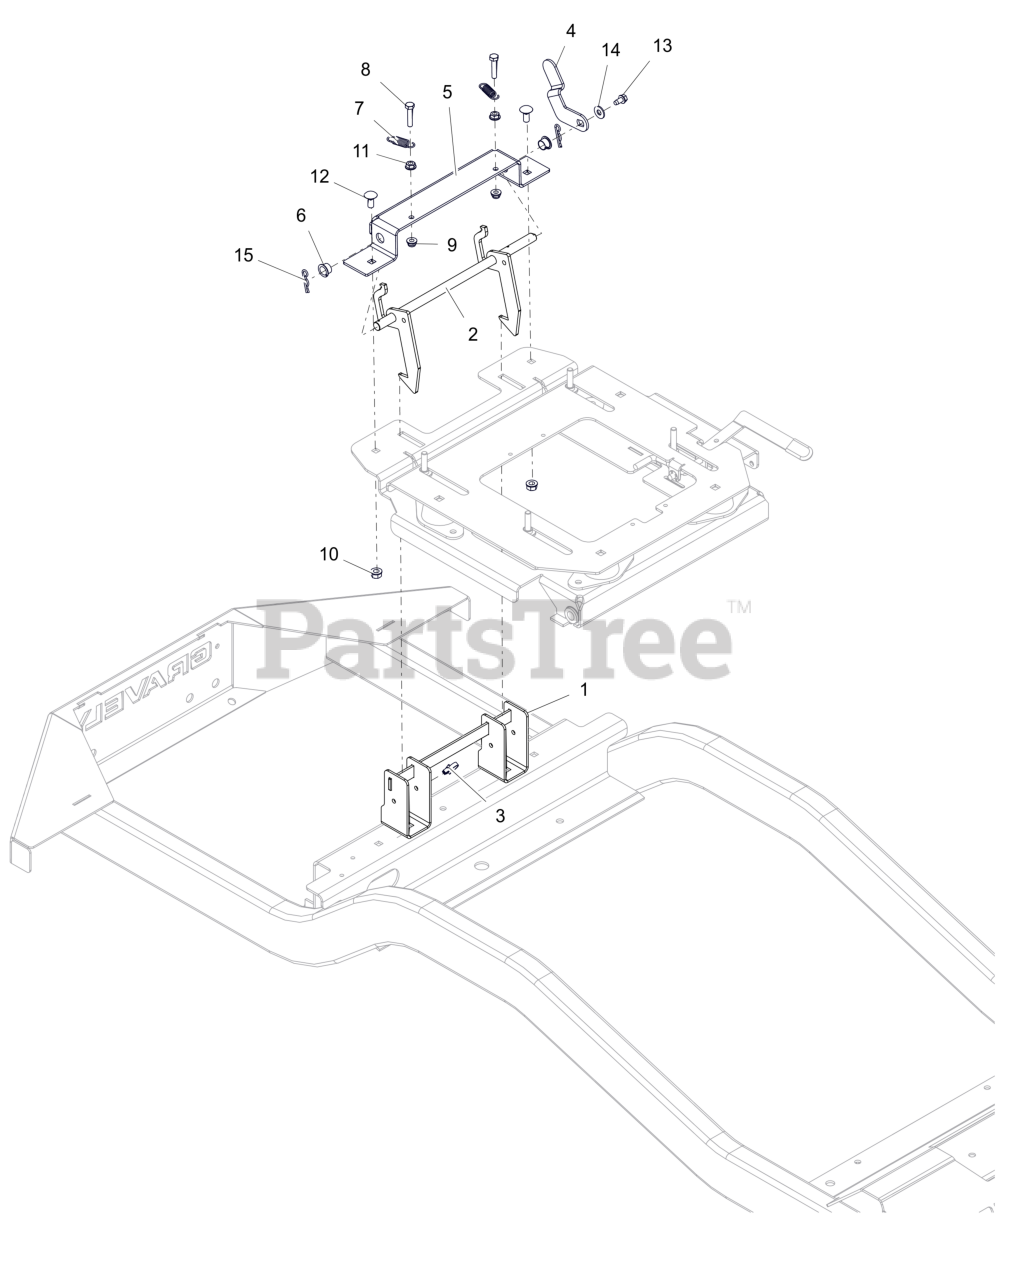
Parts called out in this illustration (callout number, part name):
1	WLDMT, LATCH RECEIVER
2	WLDMT, SEAT
3	ROUTING CLIP (1/2" ID)
4	LEVER, SEAT
5	BRKT, SEAT
6	BUSHING, POLYLINER-.50 SPLIT
7	SG-TENS .063X.44X1.56
8	BLT, HEX .25-20X1.25 G5 ZCC
9	NUT,NYL-FLG .25-20 GF ZCC
10	NUT,LK-CTR-FLG .31-18 GF ZCC
11	NUT-SPNLK-FLG .25-20 ZC120
12	BLT,RHSN .31-18X.75 G5 ZCC
13	SCR-TAP .25-20X.50 HWH ZCC
14	WSHR, FLT .312X.734X.065 ZCC
15	PIN, HAIR-INT .08X.38X1.42 ZCC
